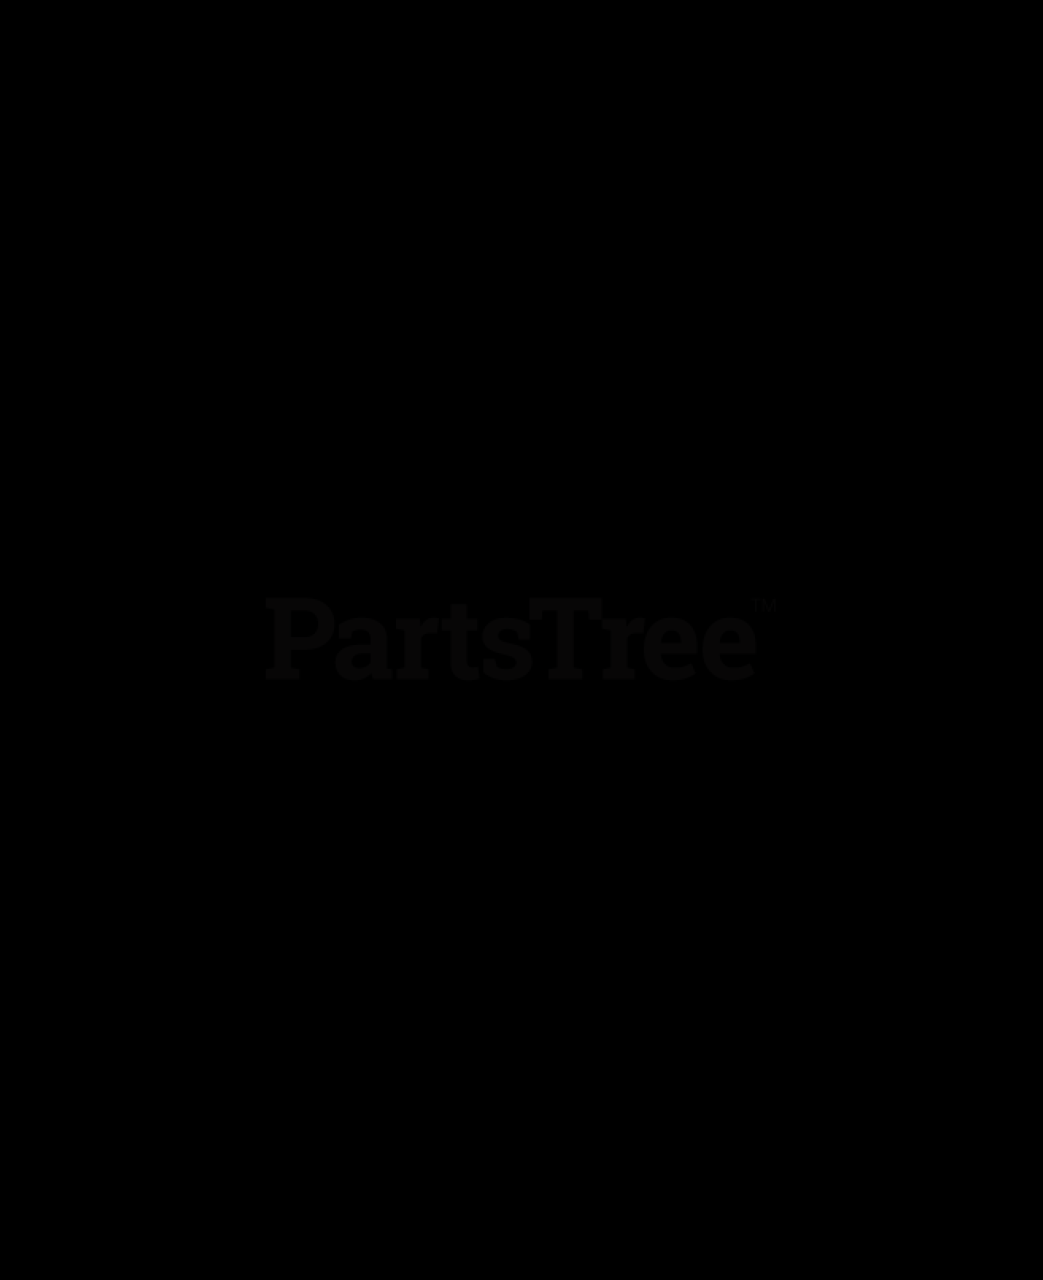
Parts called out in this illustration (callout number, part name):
1	Panel, Control
2	Screw, Machine 10-24 x .38 Hex Washer Head Stainless
3	Throttle, Control (Includes item 8)
4	Nut, Locking Nylon 10-24 with Insert
5	Bolt, Hex .31-18 x .75 Grade 5
6	Washer, Flat Steel .38 x .875 x .083
7	Screw, Machine 10-24 x .50 Hex Washer Head
8	Knob, Control, Black .38-16 x .62
9	Washer, Locking .318 x .078
